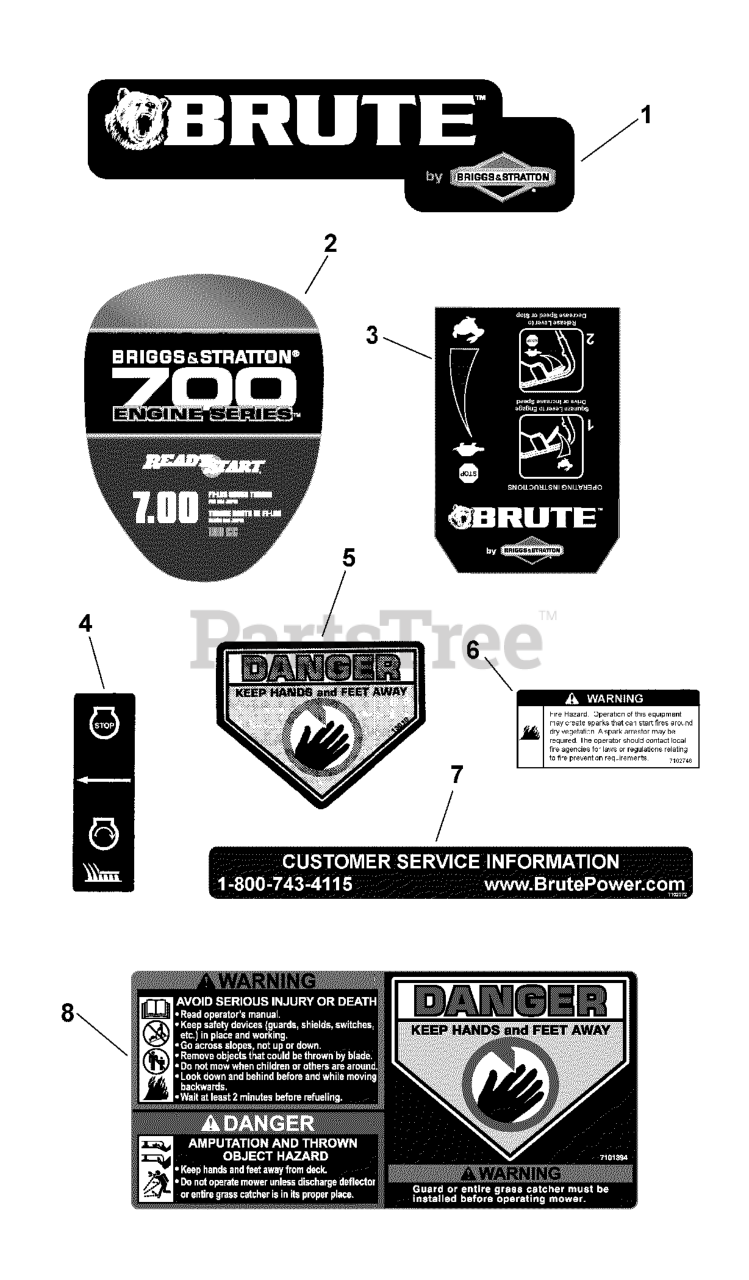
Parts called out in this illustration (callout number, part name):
1	DECAL, Brute WBM
2	DECAL, Engine, 700 Series Quantum
3	DECAL, Control Head
4	DECAL, OPC Bail International Symbol
5	DECAL, Danger, Cut Finger
6	DECAL, Spark Arrestor
7	DECAL, Customer Service, Brute
8	DECAL, Warning, Rear Discharge Door
